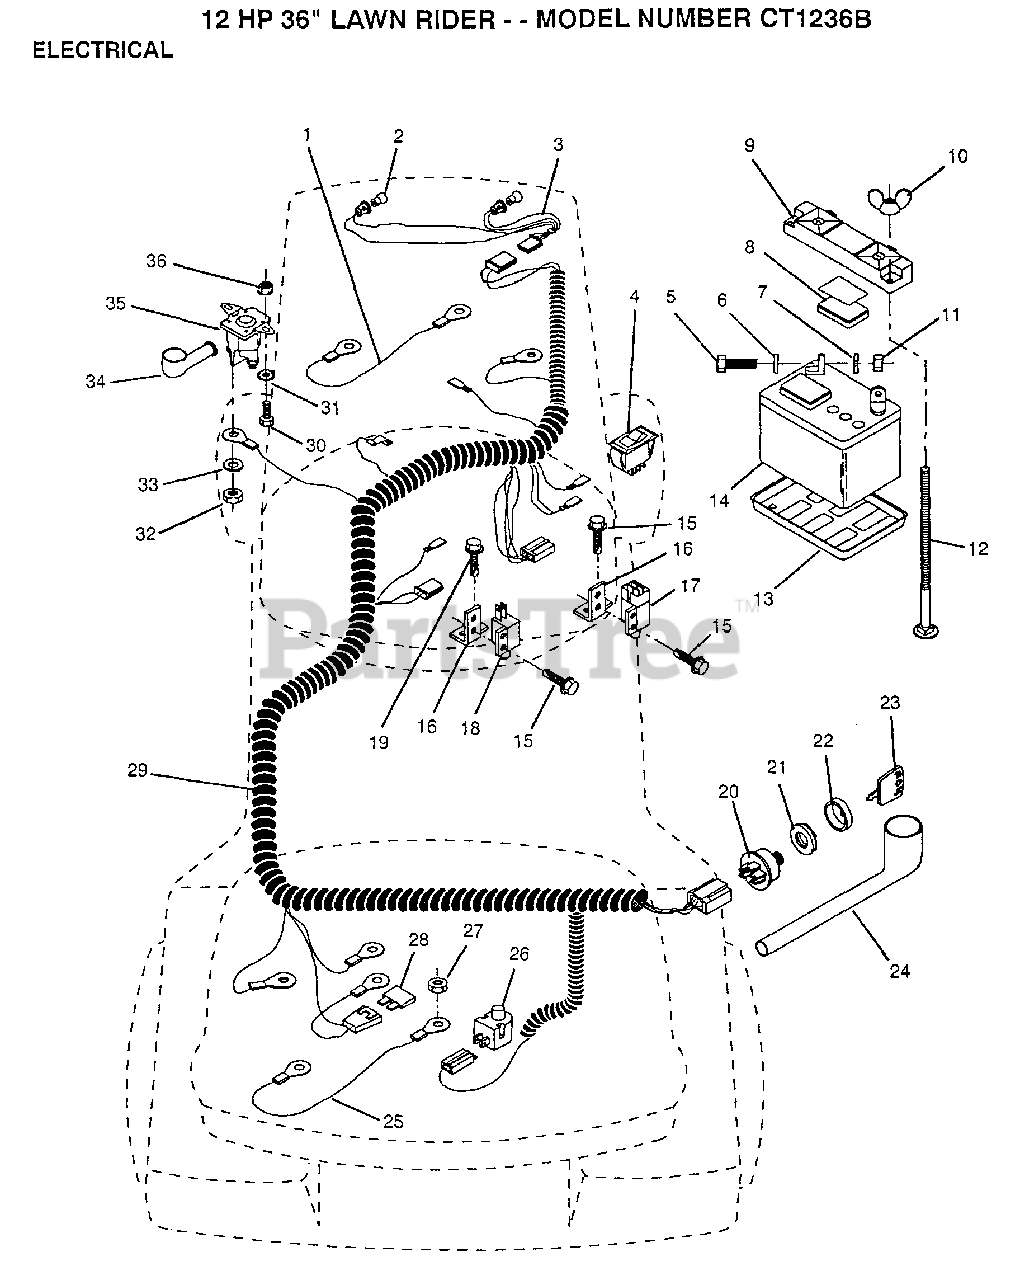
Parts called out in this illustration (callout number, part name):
1	CABLE LTV
4	SWITCH LT
5	BOLT LT
6	WASHER
7	LOCKWASHER
8	"CAP,BATTERY "
12	BOLT
13	"TRAY T, BATTERY"
15	SCREW
16	BRACKET LT
17	SWITCH INTERLOCKT
18	SWITCH-INTER. GT
19	SCREW
21	NUT IGNITION
23	KEY
24	COVER IGNITION SW
26	SWITCH SEAT
28	FUSE HYT
29	HARNESS IGNITION
30	BOLT
32	NUT
36	NUT
